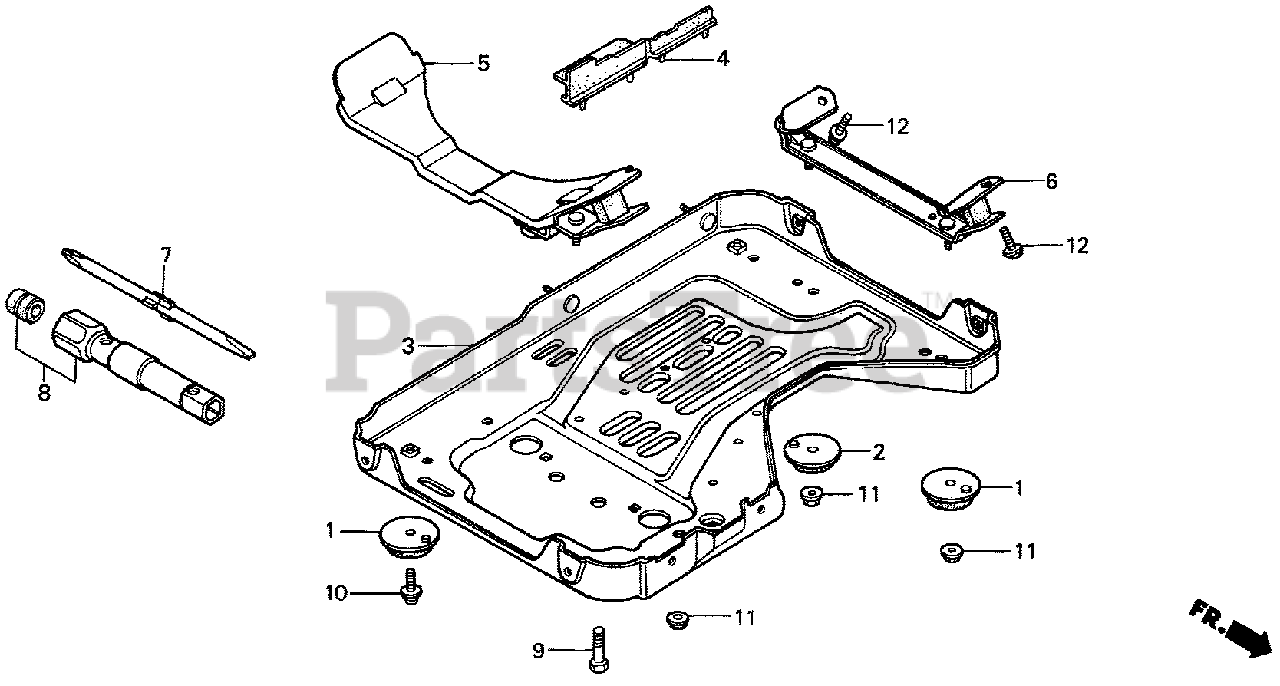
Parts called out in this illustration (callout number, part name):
1	RUBBER (LOWER)
2	DAMPER (LOWER)
3	COVER (LOWER)
4	RUBBER, AIR GUIDE (LOWER)
5	RUBBER, ENGINE MOUNTING
6	RUBBER, GENERATOR MOUNTING
7	DRIVER (NOT AVAILABLE)
8	WRENCH, BOX (P21X12)
9	BOLT-WASHER (8X16)
10	SCREW-WASHER (6X10)
11	NUT, FLANGE (6MM)
12	BOLT, FLANGE (6X12)
